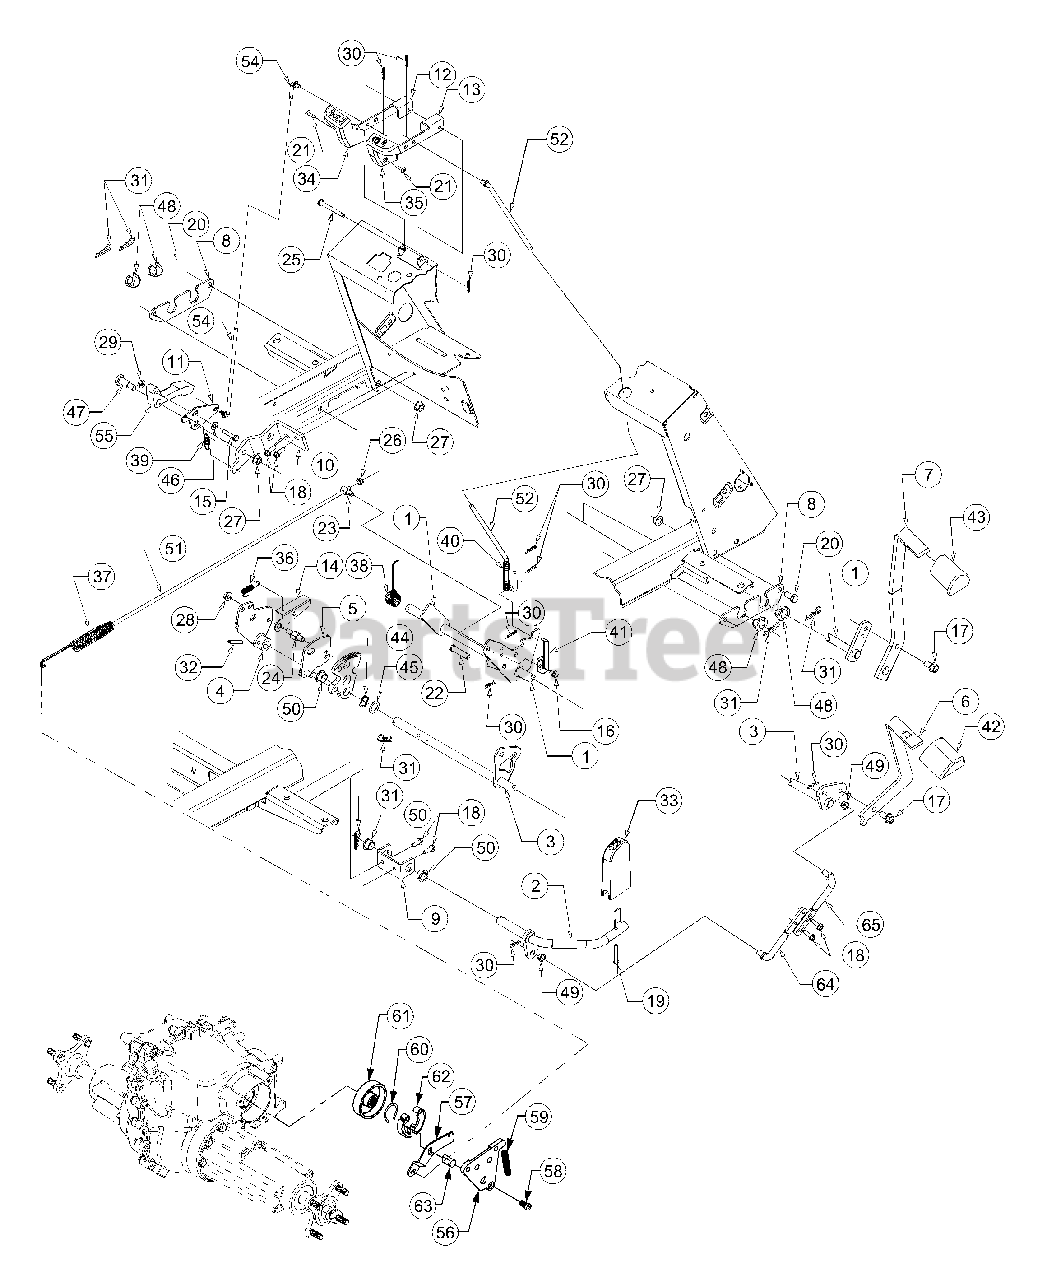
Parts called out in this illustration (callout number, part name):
1	Shaft Assy, Brake
4	Cam Assy, Control
5	Plate Assy, Disengagement
8	Plate, Bearing Mounting
10	Bracket, Cruise
11	Plate, Rod Adjustment
15	Screw, Hex Cap, 1/4-20 x 1.25
16	Screw, Hex Wash Hd Tapp 1/4-20 x .5
17	Screw, Hex Wash Hd Tapp 3/8-16x .75
18	Screw, Hex Wash Hd Tapp 1/4-20x .75
19	Screw, Truss Mach, #12 x 1.5
20	Screw, Hex Cap, 3/8-16 x .75 GR5
21	Screw, Phil Hd Pan, #10-24 x .75
22	Pin, Clevis, 3/8 x 1.62
23	Ferrule, Adjustment, 1/4-20 Thrd
24	Stud, Actuator
25	Pin, Clevis, .25 x 2.38
26	Nut, Hex Sems, 1/4-20
27	Nut, Hex Flange Lock, 3/8-16
28	Nut, Hex Flange Lock, 5/16-18
29	Nut, Hex Flange Lock, 1/4-20
30	Pin, Internal Cotter, 5/16 Dia x 1.12
31	Pin, Internal Cotter, 3/8 Dia x 1.62
32	Pin, Spiral Spring, 1/4 x 1.5
33	Pedal, Reverse
34	Knob, Cruise
35	Knob, Brake Lock
36	Spring, Extension, .38 OD x 2.1
37	Spring, Extension
38	Spring, Torsion
39	Spring, Extension, .6 OD x 1.34
40	Spring, Compression, .50 x 2.23
41	Spring, Switch Actuator
42	Pad, Forward Foot Control
43	Pad, Brake Foot
44	Washer, Wave, .625 x .885 x .015
45	Washer, Flat, .635 x 1.0 x .020
46	Washer, Flat, 1/4 x .63 x .051
47	Shoulder Bolt, .50 OD x .840
48	Bearing, Hex Flange Split
49	Bearing, Flange, .375 x .58 x .25
50	Bearing, Flange, .626 x .93 x .344
51	Rod, Brake
52	Rod, Parking Brake
54	Rod, Cruise
55	Latch, Cruise
56	Plate, Brake
57	Arm, Brake
58	Screw, Low Hd Cap, 3/8-16 x .75
59	Spring, Compression
60	Spring, Brake
61	Drum, Brake
62	Shoe, Brake
63	Actuator, Brake Shoe
64	Rod, Rear Connecting
65	Rod, Front Connecting
